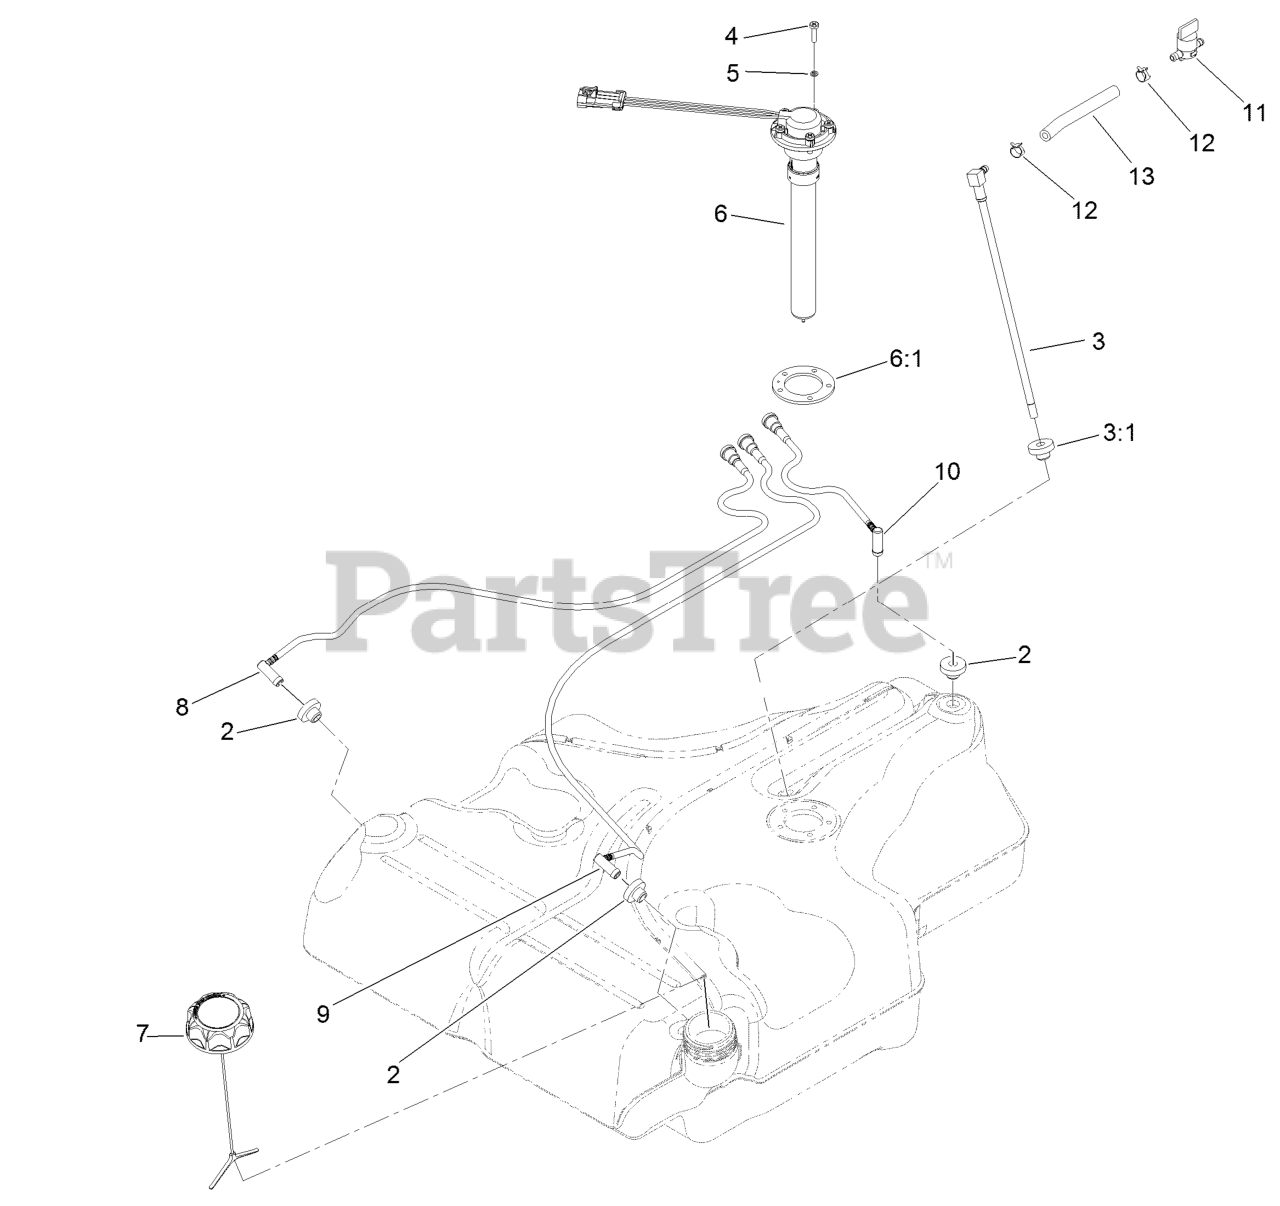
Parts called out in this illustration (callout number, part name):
2	BUSHING
3	FUEL LINE KIT (WITH GROMMET)
3:1	BUSHING
4	SCREW-PAN
5	WASHER-LOCK
6:1	GASKET-SENDER, FUEL
8	RH VENT LINE KIT (WITH GROMMET)
9	LH VENT LINE KIT (WITH GROMMET)
10	REAR VENT LINE KIT (WITH GROMMET)
11	VALVE-FUEL
12	CLAMP-HOSE
13	HOSE-FUEL
